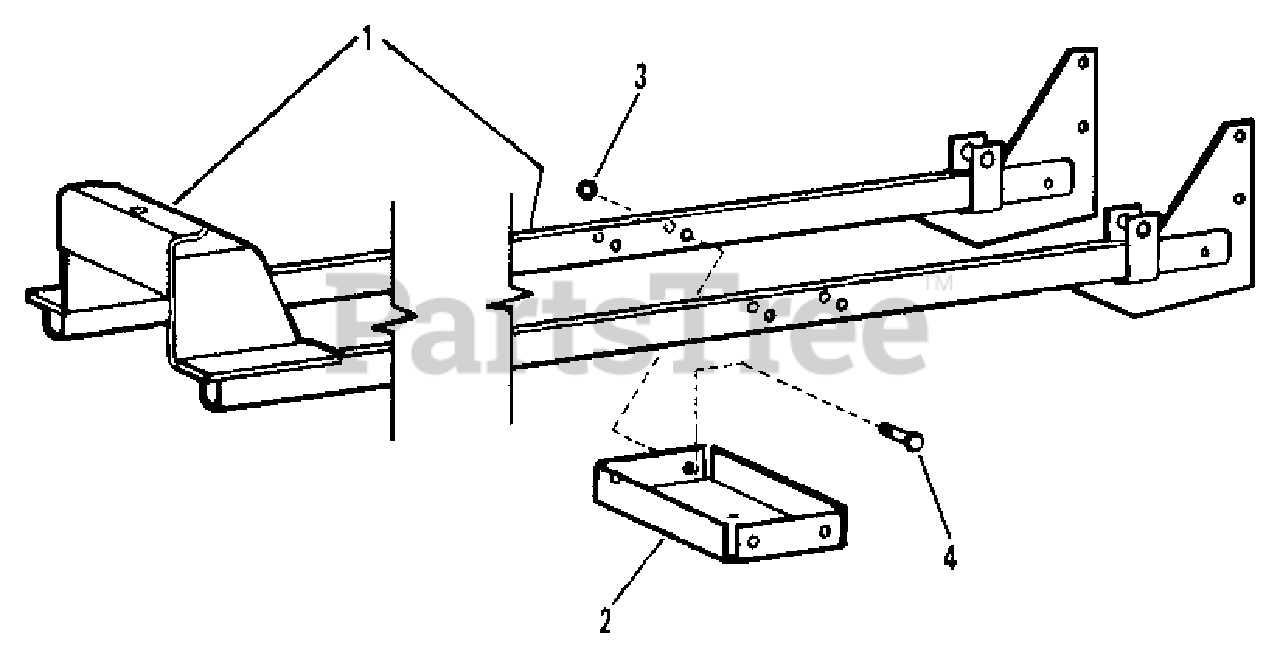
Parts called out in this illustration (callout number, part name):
1	WELDMENT, Support Tube
2	PLATE, Lower Pulley Support
3	NUT, 3/8-16 Hex Center Lock, Grade 5 or B
4	SCREW, 3/8-16 x 2" Hex Head Cap, Grade 5
